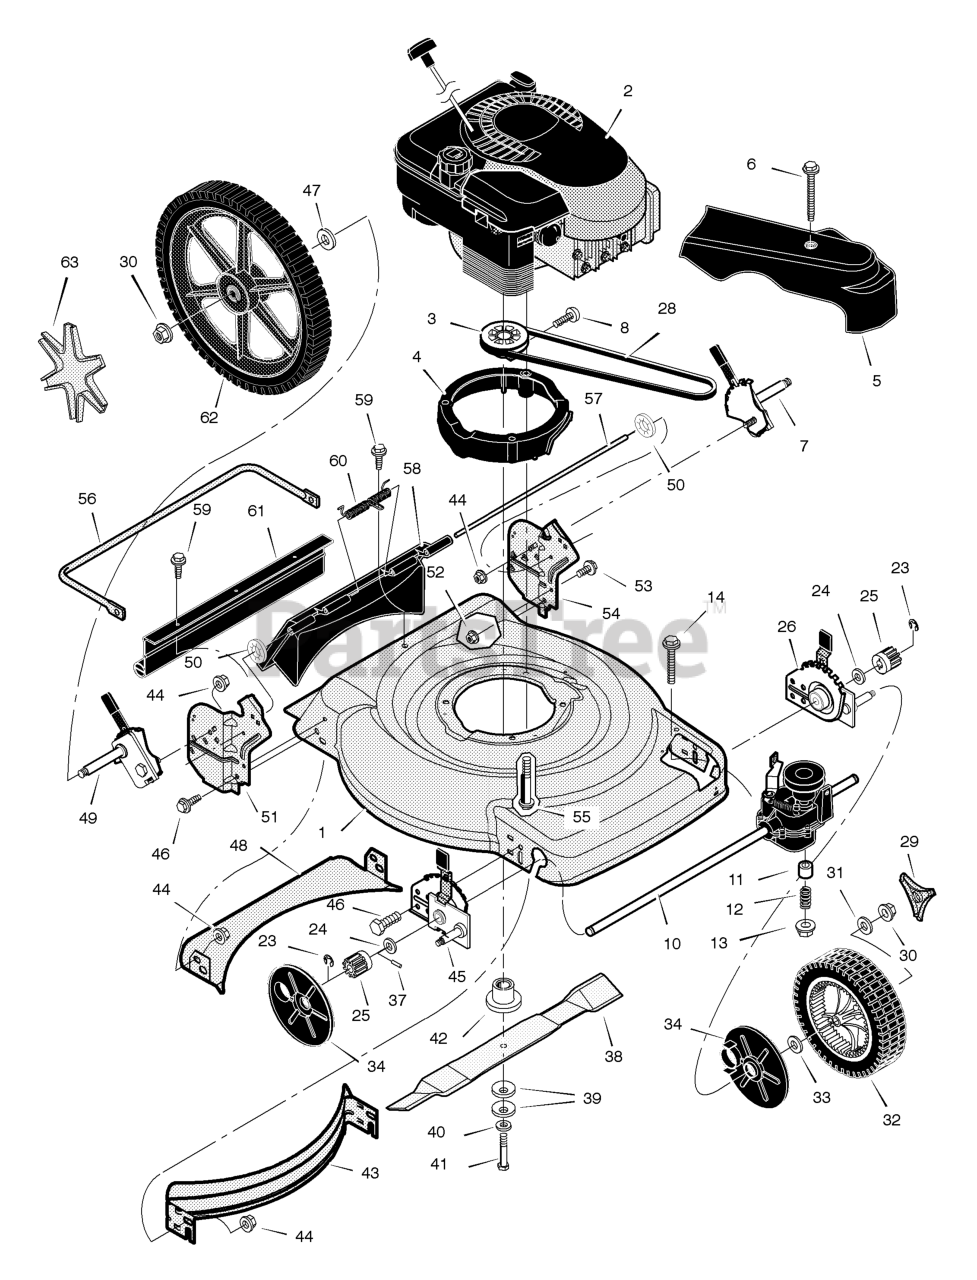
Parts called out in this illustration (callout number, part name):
1	Housing
2	Engine *
3	Pulley, Drive
4	Spacer, Engine
5	Cover, Belt (Black)
7	Adjuster, Left Rear Height
10	Transmission *
12	Spring, Compression
13	Nut
14	Bolt
25	Gear, Pinion
26	Adjuster, Left Front Height
29	Cap, Hub
30	Nut, Flange
31	Washer
32	Wheel & Tire, Front
34	Cover, Dust
37	Pin, Drive
39	Washer, Belleville
42	Adapter, Blade
43	Baffle, Front
44	Nut, Flange
45	Adjuster, Right Front Height
46	Bolt
48	Baffle, Rear
49	Adjuster, Right Rear Height
50	Retainer, Push
51	Bracket, Right Handle
52	Nut, Flange
53	Bolt
54	Bracket, Left Handle
55	Bolt, Engine
57	Rod, Pivot
58	Door, Rear (Black)
60	Spring
61	Guard, Rear
62	Wheel & Tire, Rear
63	Hub Cap, Rear
